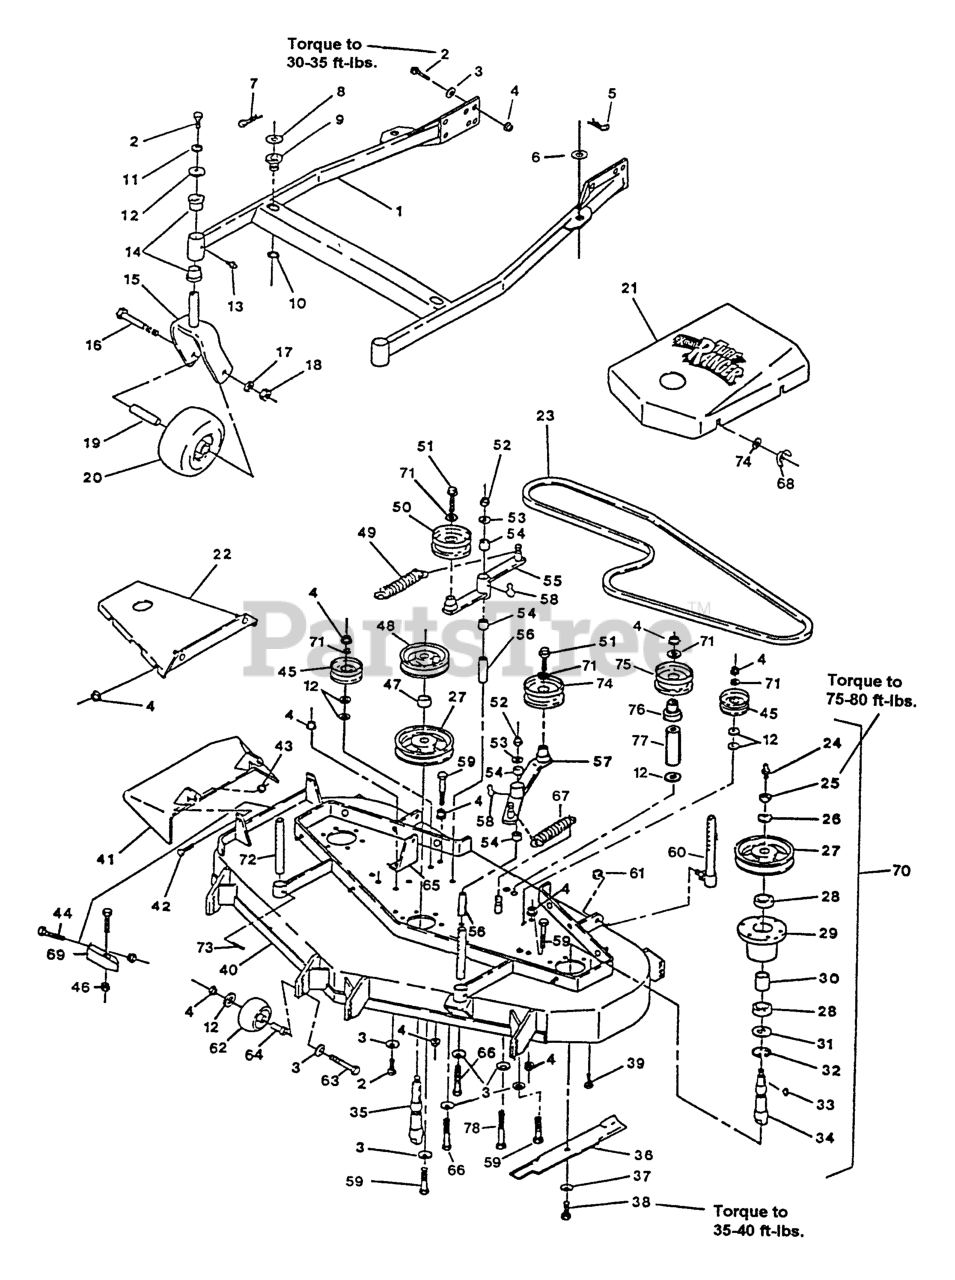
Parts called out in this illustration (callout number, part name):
5	PIN,HAIR COTTER
8	WASHER-FLAT
9	BUSHING-DECK
12	WASHER
14	BEARING-FLANGED
23	BELT,BLADE DRIVE
26	WASHER-SPRING
27	SHEAVE,BLADE DRIVE
28	BEARING,HD SPINDLE
30	SPACER,BEARING
31	SEAL,MECHANICAL DUST
32	RING,SNAP WLDS N5000-244
34	SPINDLE-OUTER BLADE
35	SPINDLE-CENTER BLADE
37	WASHER-SPRING
39	SCRW,TPTTE HH
41	WLD,CHUTE DISCHARGE
45	IDLER,PULLEY
47	SPACER-TUBE
48	SHEAVE,MOWER DRIVE
49	SPRING-EXTENSION
50	IDLER,PULLEY
54	SLEEVE-BEARING
55	ASM,IDLER ARM
56	BUSHING-PIVOT, IDLER
57	ASM,IDLER ARM
62	ROLLER-SCALP, ANTI
64	BUSHING-ROLLER
65	BRACKET,SPRING ANCHOR
66	SCREW-HH
67	SPRING-EXTENSION
68	NUT-WING
69	WLD,BAFFLE DISCHARGE
72	ROD,DECK SUPPORT
74	PULLEY-IDLER
75	PULLEY-IDLER
76	BUSHING,IDLER
77	SPACER-FENDER
